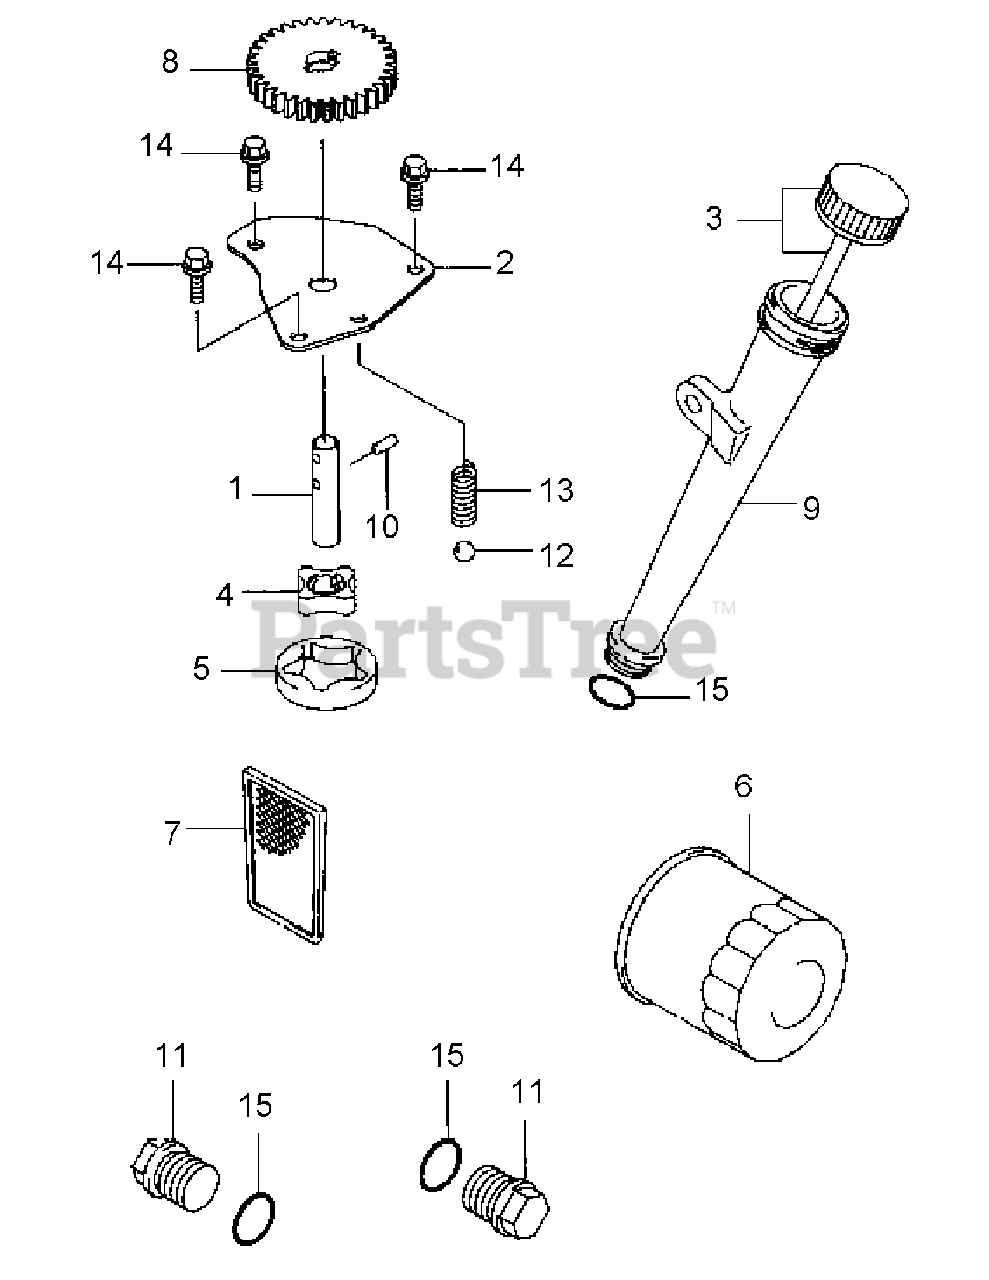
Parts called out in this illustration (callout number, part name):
1	SHAFT
3	CAP-ASSY
4	ROTOR-PUMP, IN
5	ROTOR-PUMP, OUT
6	FILTER-OIL
7	FILTER-OIL
10	PIN
11	PLUG
14	BOLT-FLANGED
15	O RING, 16MM
